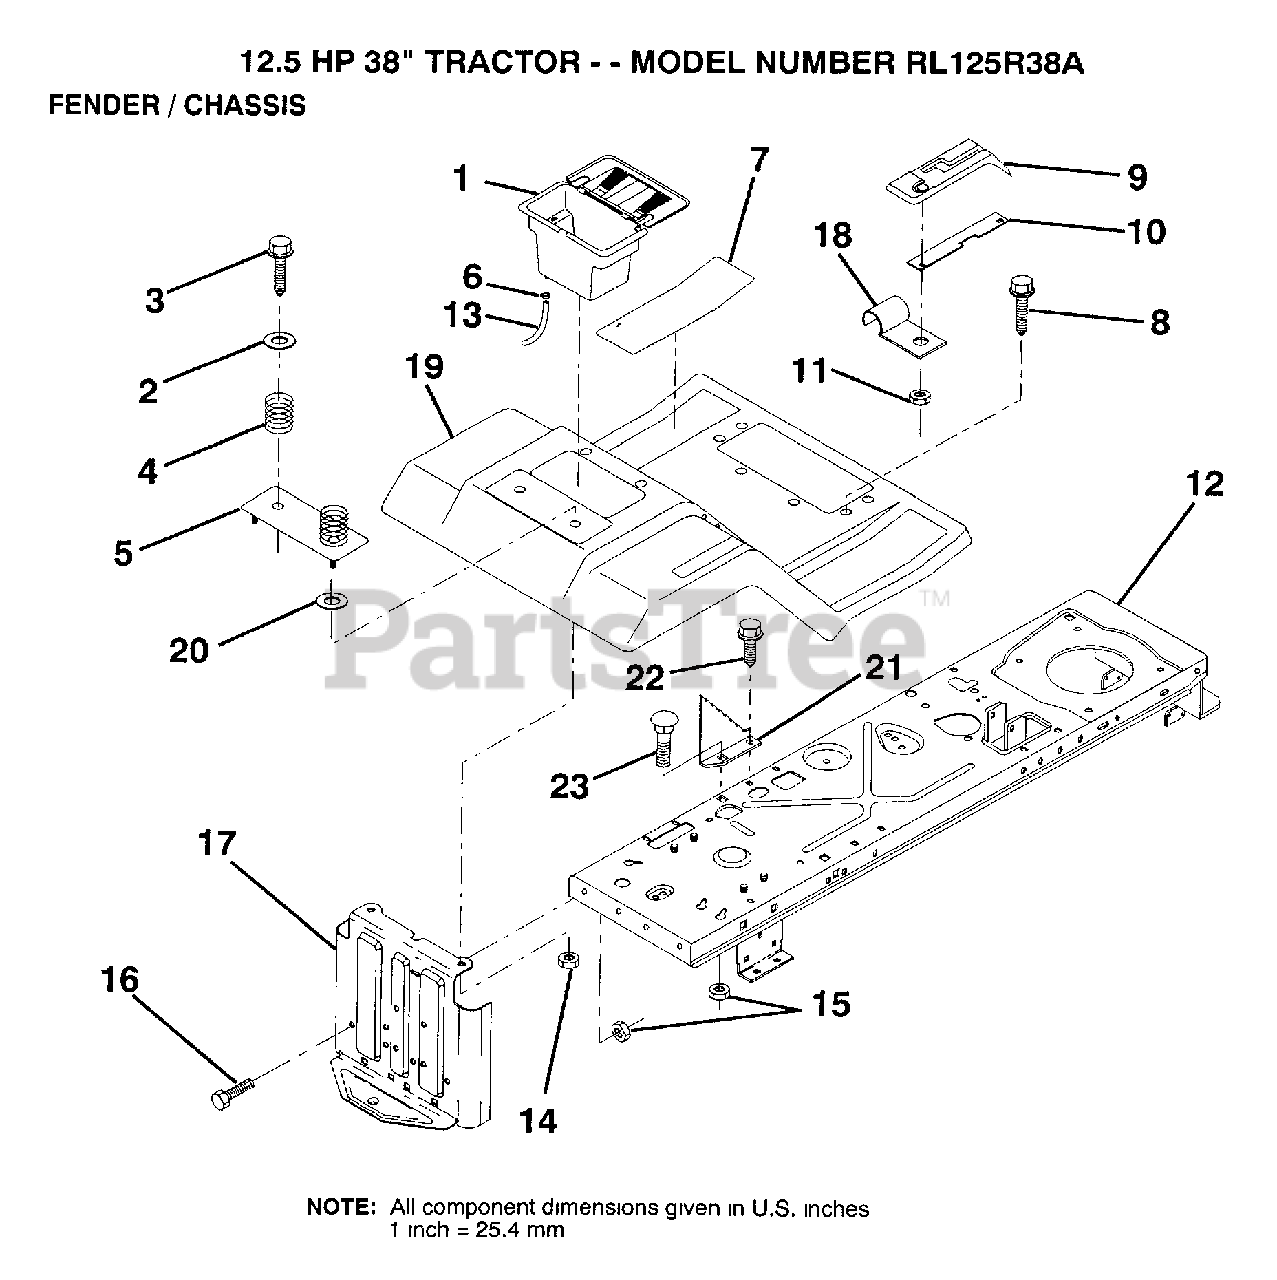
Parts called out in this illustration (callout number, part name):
2	WASHER
3	SCREW
4	SPRING COMPRESSIO
5	"PLATE, BATTERY"
6	HOSE CLAMP T
7	PAD FOOTREST
8	SCREW
10	"SHIFT LOCK, BAR"
11	NUT
14	NUT
16	BOLT
17	DRAWBAR
18	"CLIP,INSULATOR"
22	SCREW LT
